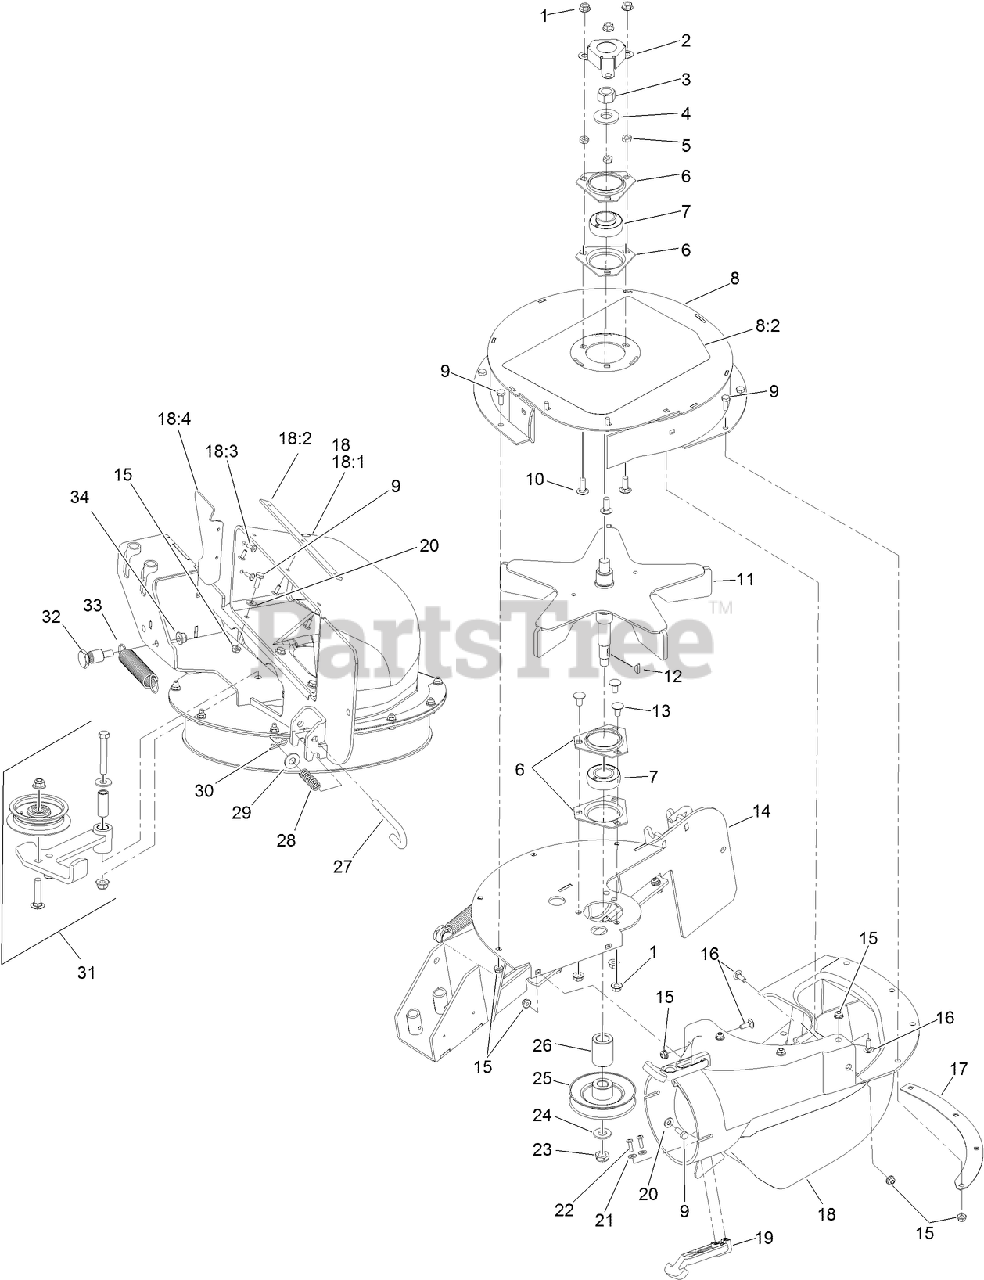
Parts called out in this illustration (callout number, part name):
1	NUT-HF
2	COVER-NUT
3	NUT-HEX
4	WASHER-SPRING
5	NUT-JAM
6	HOUSING-FLANGE
7	BEARING
8	UPPER HOUSING ASM
8:2	DECAL-WARNING, BLOWER
9	SCREW-HH
10	BOLT-CARR
11	IMPELLER
12	KEY-WOODRUFF
13	SCREW-CARR
14	FRAME-BLOWER
15	NUT-HF
16	BOLT-CARR
17	PLATE-BACKING
18	BLOWER CHUTE ASM
18:1	CHUTE-BLOWER, SMALL
18:2	PLATE-REINFORCEMENT
18:3	RIVET-BLIND
18:4	PLATE-FILLER
19	LATCH-RUBBER
20	WASHER-FLAT
21	WASHER-FLAT
22	SCREW-PPH
23	NUT-LOCK, NI
24	WASHER-FLAT
25	PULLEY
26	SPACER
27	PIN-LATCH
28	SPRING-COMPRESSION
29	WASHER-FLAT
30	PIN-COTTER
31	IDLER ARM ASM
32	ANCHOR-SPRING
33	SPRING-EXTENSION
34	NUT-HF, NI
